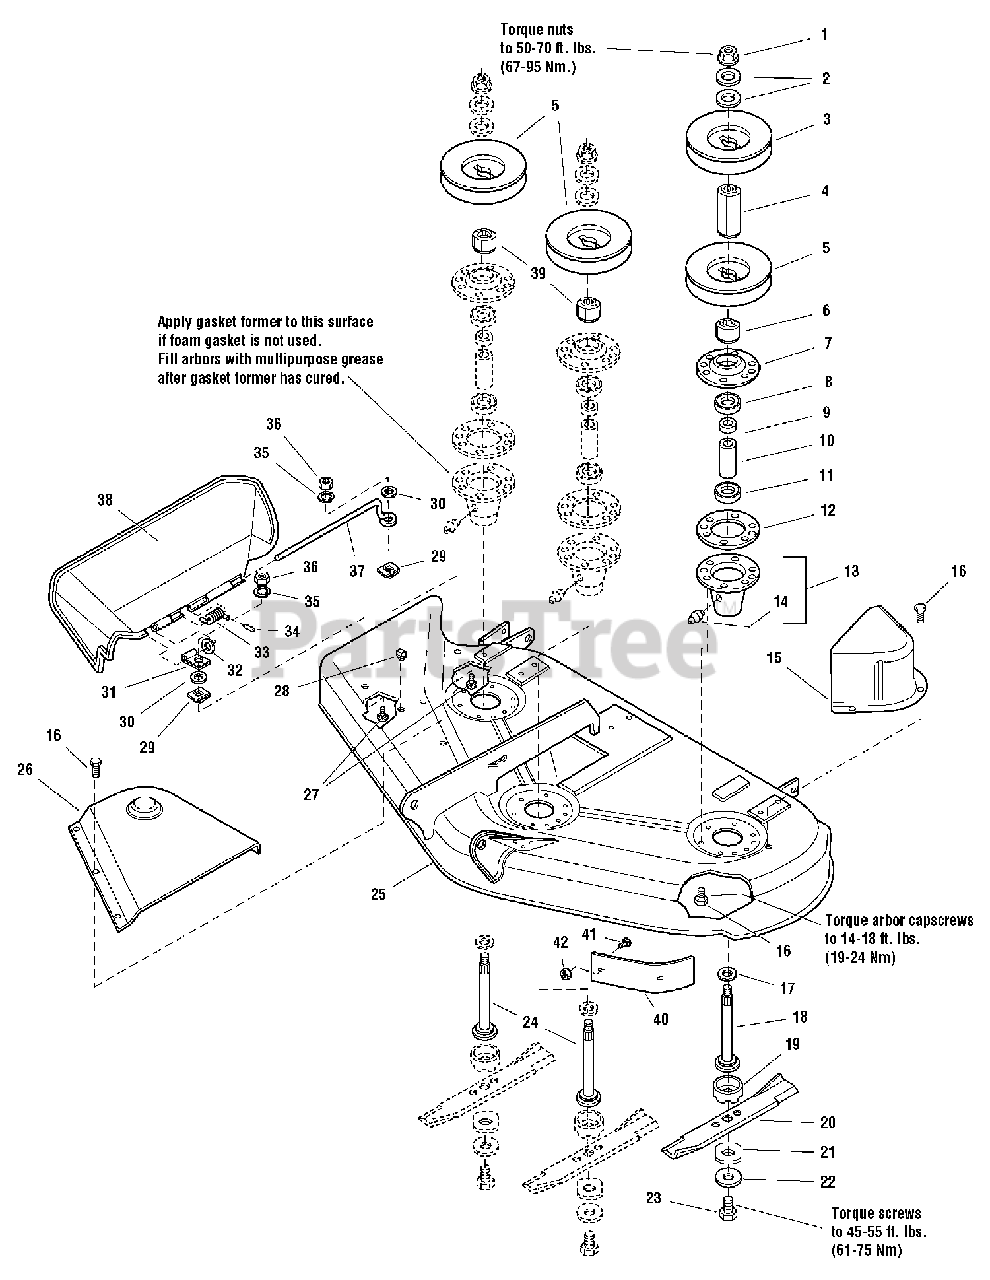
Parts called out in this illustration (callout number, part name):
1	NUT, Hex Flange, 9/16-18
2	WASHER, Bellville, 9/16
3	PULLEY
4	HUB, Double Pulley
5	PULLEY
6	HUB, Double Pulley
7	COVER, Arbor Housing
8	BEARING, Ball, 3/4 x 1-3/4 x 5/8
9	SPACER, 21/32 x 3/4 x 5/8
10	SPACER, 11/16 x 5/32 x 2-11/16
11	BEARING, Ball, 11/16 x 1-9/16 x 15/32
12	GASKET, Foam
13	ARBOR HOUSING ASSEMBLY, (Includes Ref. No. 14)
14	FITTING, Grease
15	COVER, Arbor
16	CAPSCREW, Hex Head Taptite, 5/16-18 x 3/4
17	WASHER, Bellevilled, 9/16, Black
18	SHAFT, Arbor (LH)
19	SHIELD, Grass, Lower
20	BLADE, Mower, 18-1/8
21	WASHER, Hex, 11/16 x 2
22	WASHER, Spring 15/32, Black
23	CAPSCREW, Hex Head, 7/16-14 x 1
24	SHAFT, Arbor (Center & RH)
25	MOWER HOUSING ASSEMBLY, 50" Mower (Orange)
25	MOWER HOUSING ASSEMBLY, 50" Mower (Red)
26	COVER, Arbor
27	CARRIAGE BOLT, 1/4-20 x 7/8
28	PLUG, Hole
29	NUT, Push
30	WASHER, 1/4, Black
31	CLAMP
32	WASHER, 5/16, Black
33	SPRING
34	CAP, Spring End
35	WASHER, Lock, 1/4
36	NUT, Hex, 1/4-20
37	ROD, Deflector, Front
38	DEFLECTOR, Plastic
39	HUB, Pulley, Center & RH
40	BAFFLE, Anti-Blowout
41	NUT, Hex, Whizlock, 5/16-18
42	CARRIAGE BOLT, 5/16-18 x 3/4
